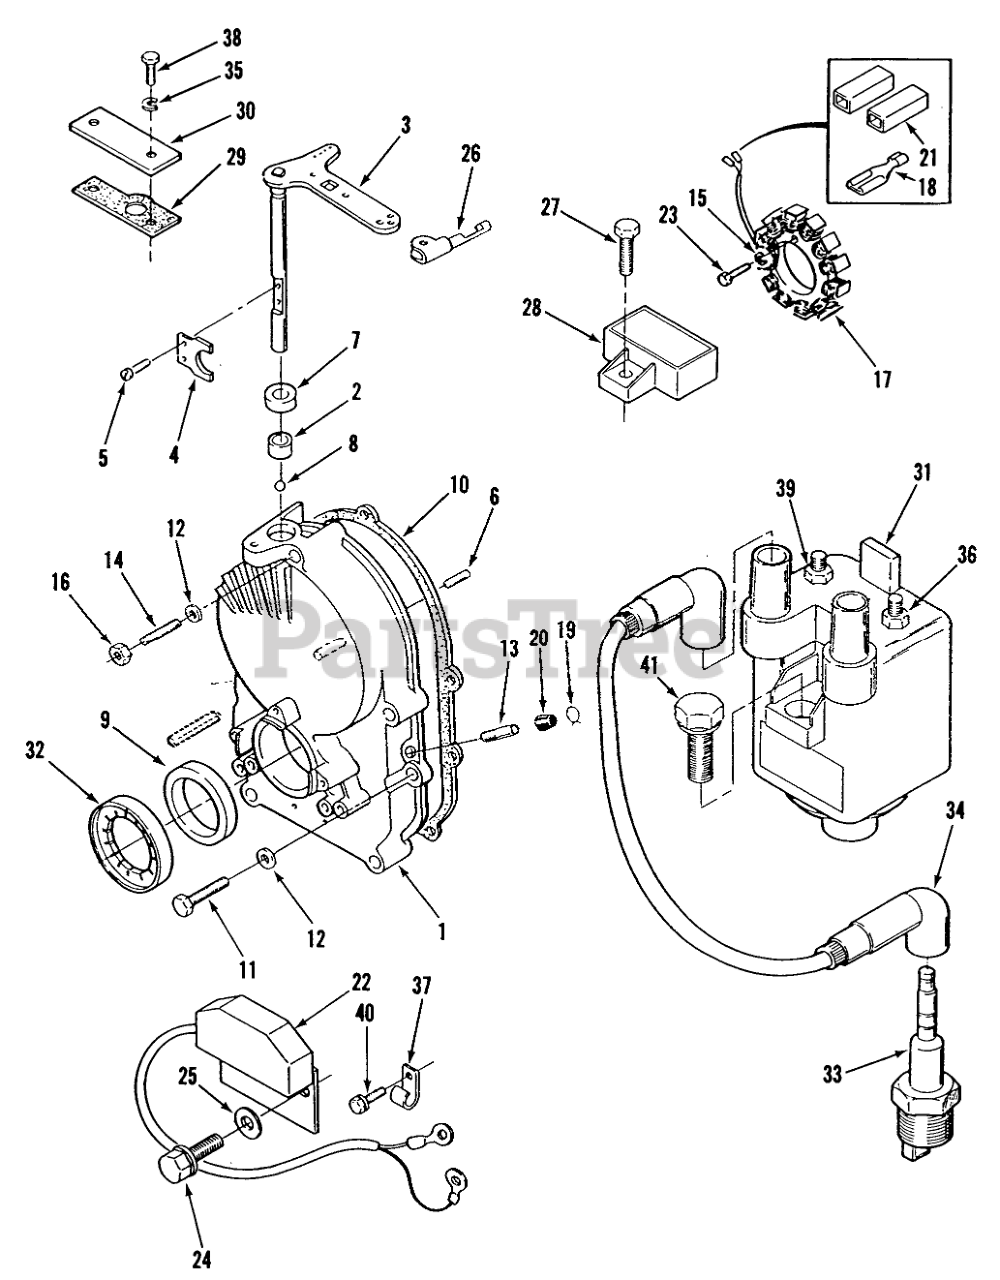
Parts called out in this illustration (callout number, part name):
1	Gearcase Kit (Includes Items 2 thru 9, 13, 19 & 20)
2	Bearing, Governor Shaft
3	Governor Shaft and Arm-Chromed
4	Yoke, Governor Shaft
5	Screw, Machine-Pan Hd.
6	Pin, Dowel-Governor Cup Stop
7	Seal, Oil-Governor Shaft
8	Ball, Bearing-Governor Shaft
9	Seal, Oil-Crankshaft
10	Gasket, Gearcase Mounting
11	Hex Hd. Cap Screw 5/16-18 x 1-3/4
12	Washer, Flat Copper
13	Tube, Vacuum Port
14	Stud, Gear Cover-Top Hole
15	Washer-Lock
16	Nut 5/6-18
17	Stator (Incl. Ref. #15 & 20)
18	Terminal, Stator Leads
19	Clamp, Hose
20	Cap, Fuel Outlet
21	Terminal Connector Body Kit (Includes Terminals)
22	Ignition Control
23	Self-Lock Hex Hd. Mach. Screw No. 10-32x1
24	Hex Washer Hd. Screw No. 10-32 x 3/8
25	Washer, Lock Internal Tooth
26	Clip, Retaining-Control Rod
27	Screw, Cup Hex Washer Hd.
28	Voltage Regulator-20 amp
29	Gasket, Breaker Box
30	Ignition Plunger Cover
31	Battery Ignition Coil w/Nuts
32	Ignition Rotor
33	Plug, Spark
34	Spark Plug Cable-9" Long
35	Washer, Lock
36	Hex Flange Nut
37	Wire Clip
38	Hex Hd. Cap Screw 1/4-20 x 5/8
39	Hex Flange Nut
40	Hex Washer Hd. Screw 1/4-20 x 1
41	Hex Washer Hd. Screw 1/4-20 x 1
